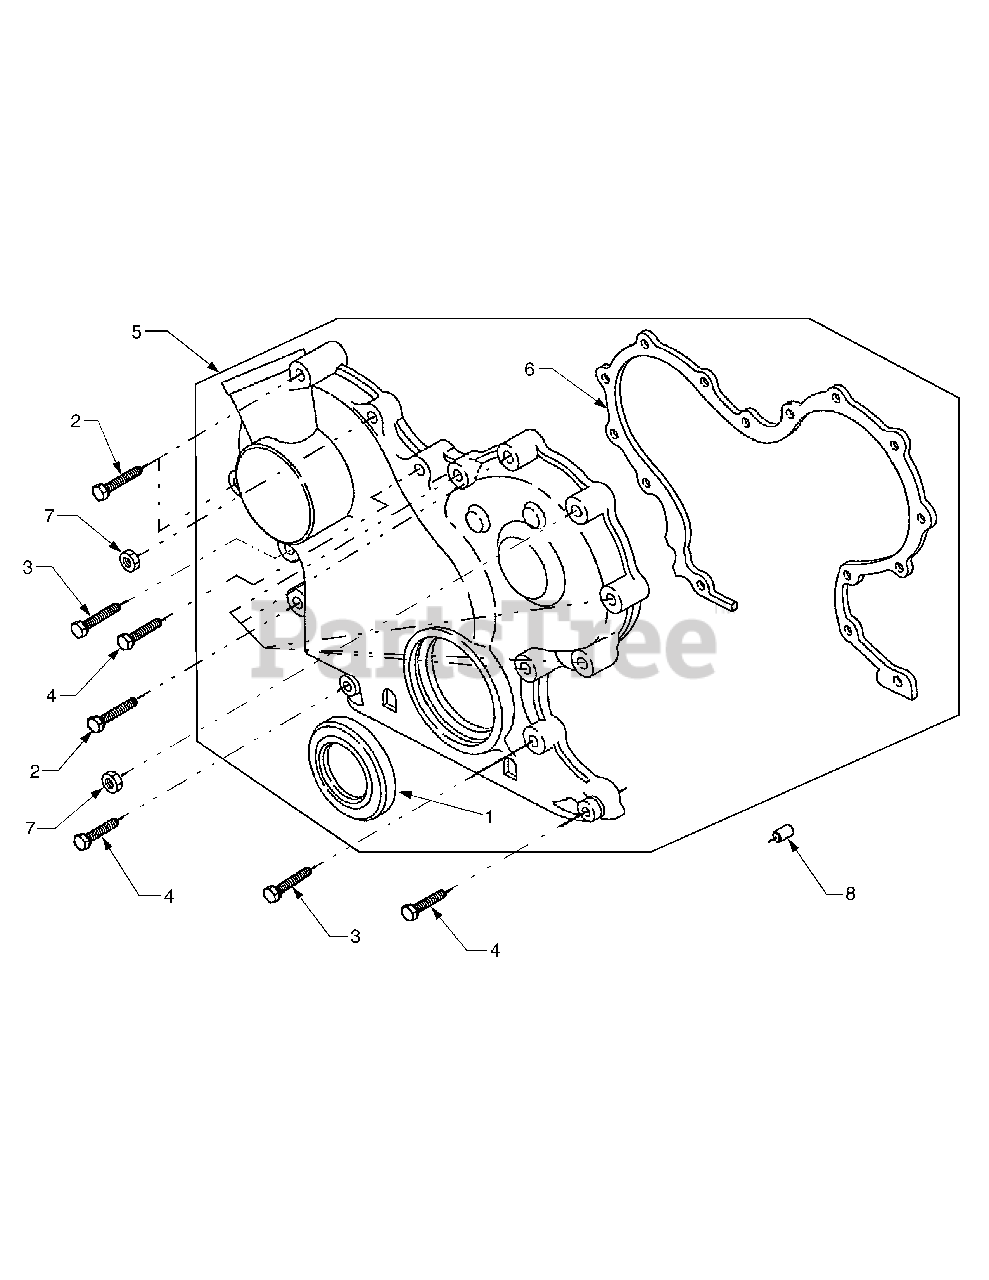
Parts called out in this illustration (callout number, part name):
2	Screw, Hex, 6mm
3	Screw, Hex, 6mm
4	Screw, Hex, 6mm
5	Cover Assembly, Gear
6	Gasket, Gear Cover
7	Nut, Hex Metric
8	Pin, Locating
